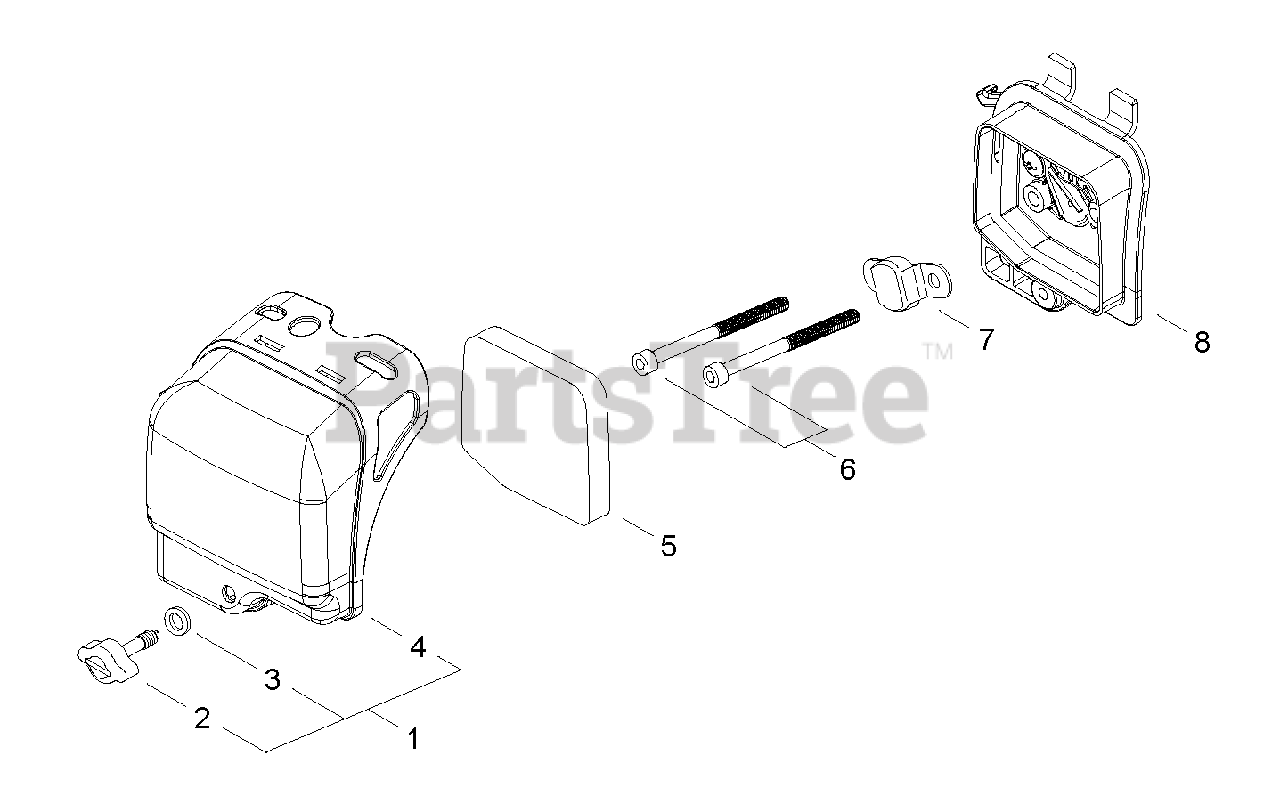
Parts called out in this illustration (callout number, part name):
1	COVER ASSY, AIR FILTER
2	THUMBSCREW
3	WASHER 5
4	COVER, AIR FILTER
5	FILTER, AIR
6	BOLT M5×60
7	BRACKET
8	BASE ASSY, AIR FILTER
